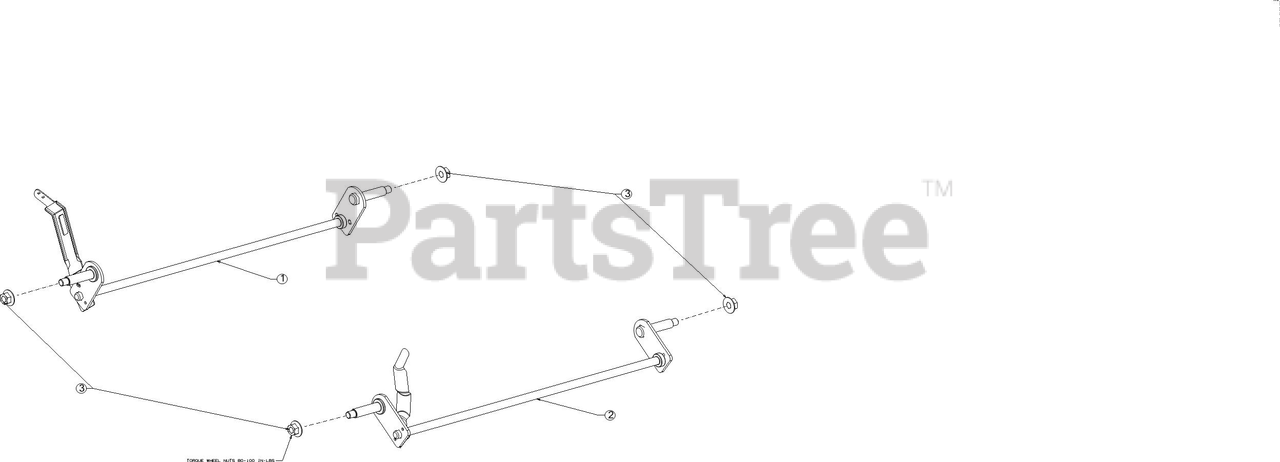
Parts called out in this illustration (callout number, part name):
1	8" REAR AXLE ASSEMBLY
2	7" FRONT AXLE ASSEMBLY
3	FLANGE LOCK NUT
